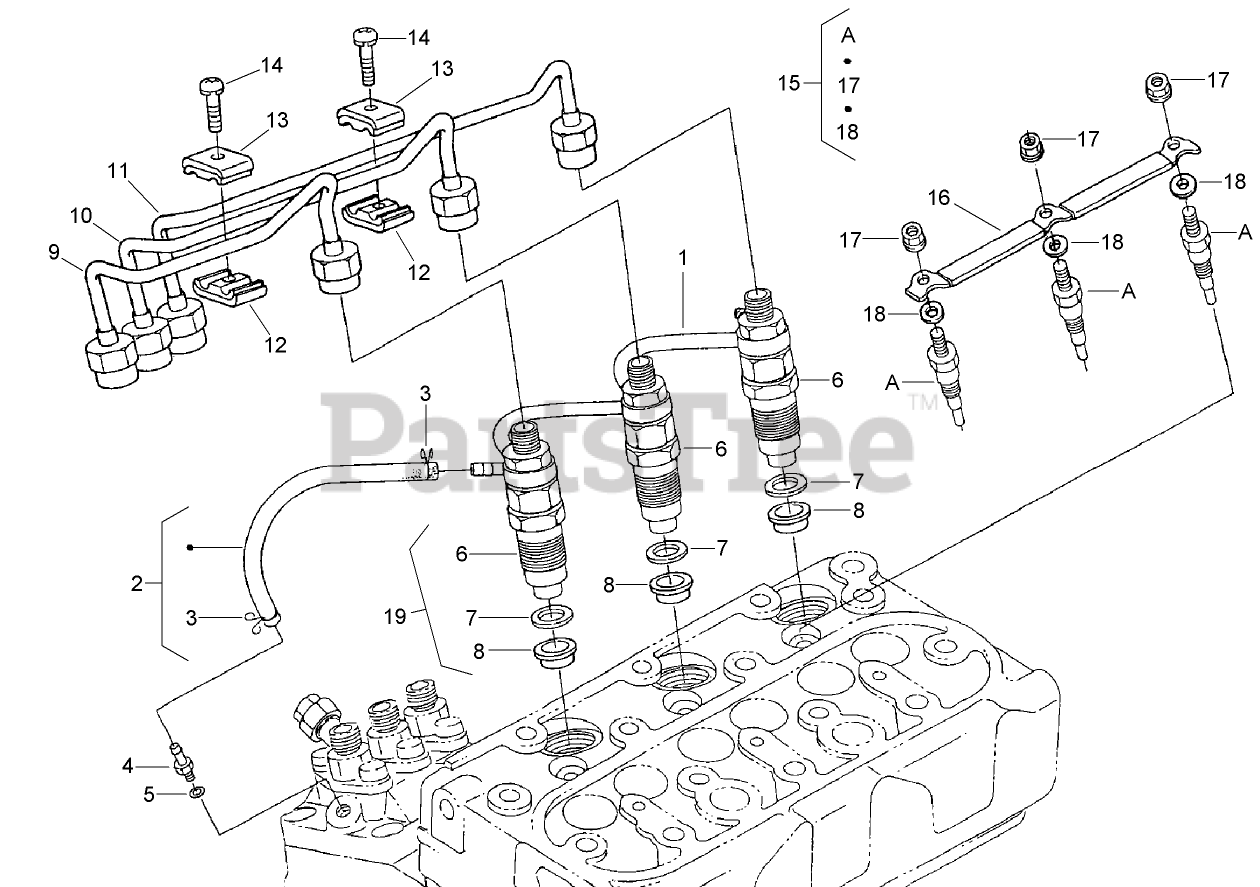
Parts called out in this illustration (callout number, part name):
1	OVER FLOW PIPE ASM
2	OVERFLOW PIPE ASM
3	CLIP-PIPE
4	SCREW-BLEEDER, AIR
5	GASKET
6	NOZZLE HOLDER ASM
7	GASKET
8	SEAL-HEAT
9	PIPE-INJECTION
10	PIPE-INJECTION
11	PIPE-INJECTION
12	CLAMP-PIPE
13	CLAMP-PIPE
14	SCREW (W/WASHER)
15	PLUG-GLOW
16	CORD-PLUG, GLOW
17	NUT-FLANGE
18	WASHER-PLAIN
19	NOZZLE HOLDER KIT
